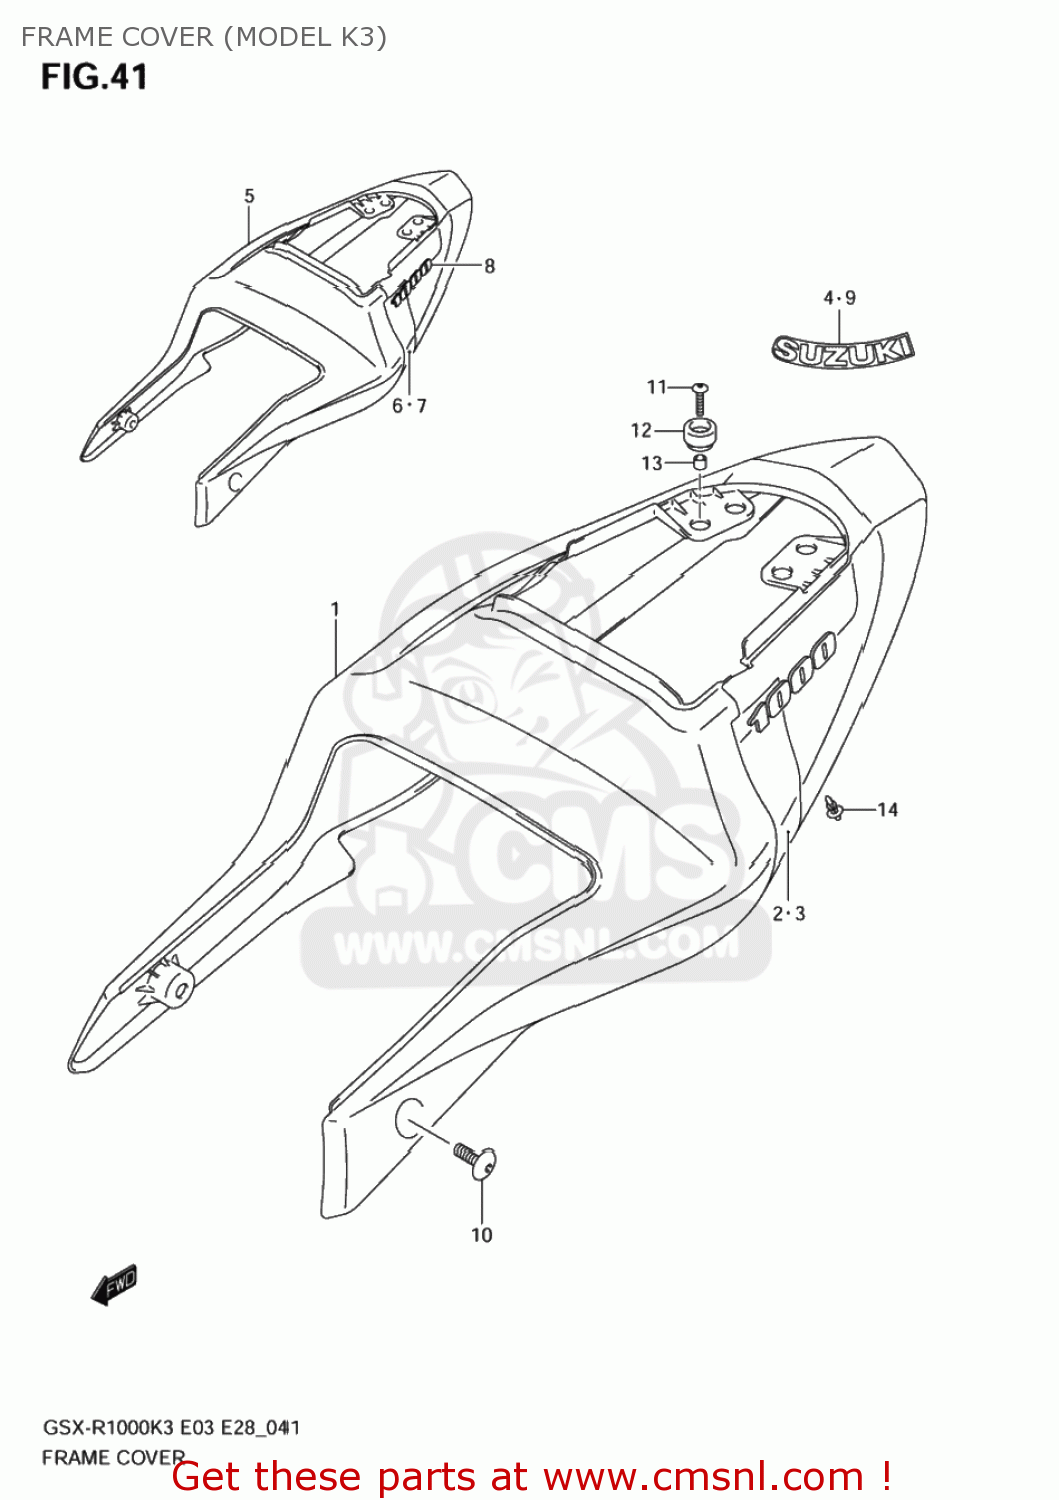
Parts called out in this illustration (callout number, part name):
1	COVER ASSY,FRAME(WHITE)
2	TAPE,FRAME COVER,R
3	TAPE,FRAME COVER,L
4	EMBLEM,SUZUKI
5	COVER ASSY,FRAME(SILVER)
6	TAPE,FRAME COVER,R
7	TAPE,FRAME COVER,L
8	EMBLEM,1000
9	EMBLEM,SUZUKI
10	SCREW(6X16)
11	SCREW(6X25)
12	CUSHION
13	SPACER(6.5X10X9.4)
14	CLIP(BLACK)
